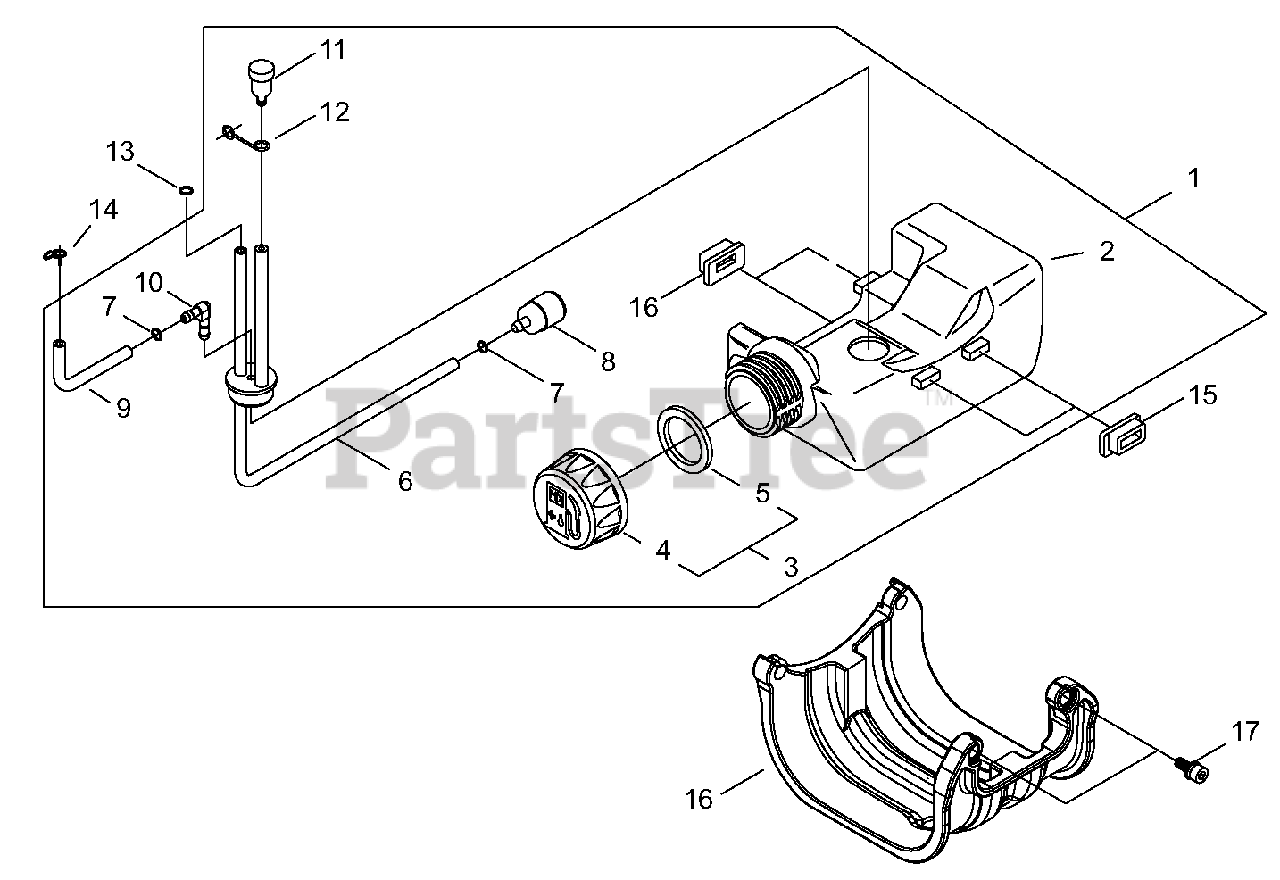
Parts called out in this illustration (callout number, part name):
1	FUEL TANK ASSY
2	TANK, FUEL
3	CAP ASSY
4	CAP, FUEL
5	GASKET, CAP
6	PIPE - FUEL
7	CLIP - 6
8	FILTER, FUEL
9	PIPE - RETURN
10	CONNECTOR, PIPE
11	VENT, FUEL TANK
12	HOLDER, VENT
13	CLIP - 6
14	CLIP - BUTTERFLY
15	CUSHION, FUEL TANK
16	GUARD, FUEL TANK
17	SCREW - 5X16
